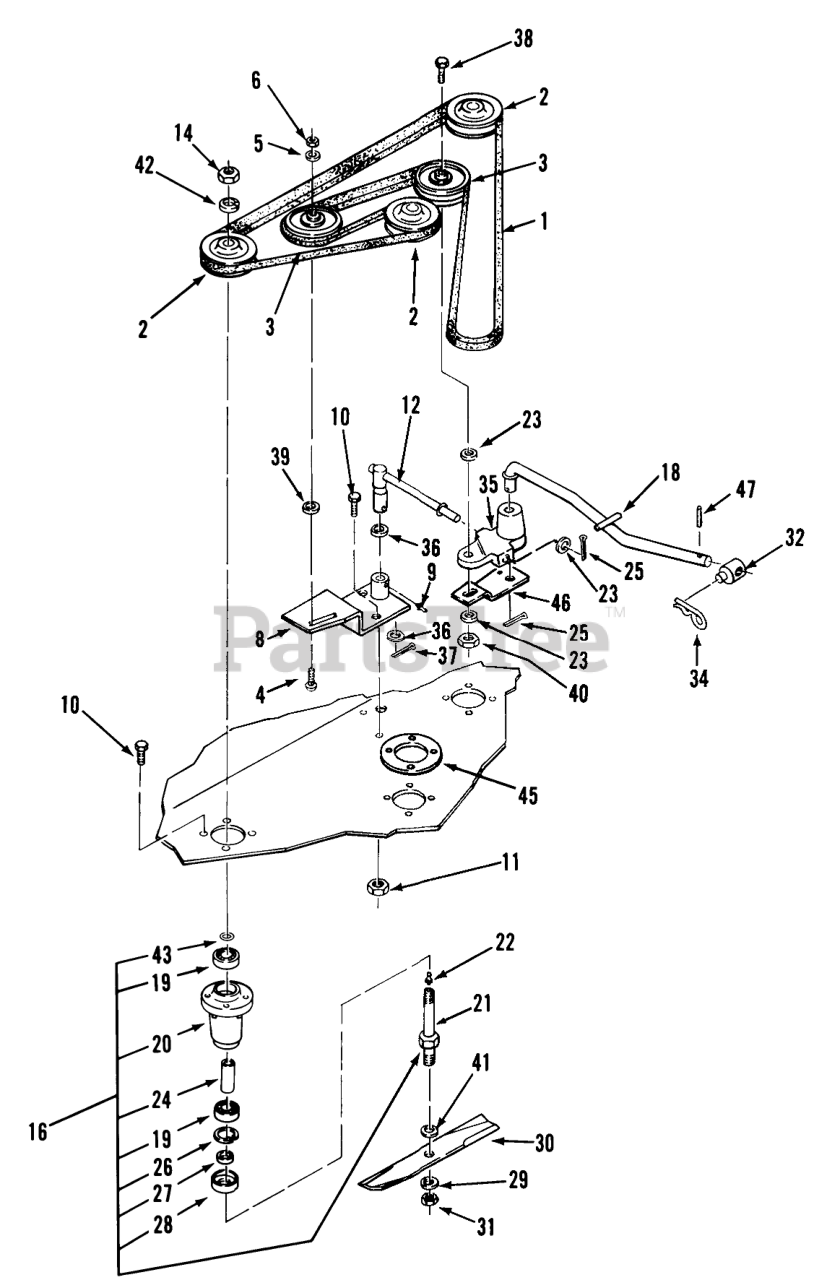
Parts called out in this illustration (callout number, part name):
1	BELT-MOWER
2	PULLEY-BLADE
3	PULLEY-FLAT IDLER
4	Carriage Bolt 3/8-16 x 2
5	Washer
6	NUT
8	Idler Bracket
9	FITTING-GREASE
10	Bolt
11	NUT
12	ASS'Y-IDLER ARM B
14	Jam Nut
16	Spindle Assembly (includes items 19 thru 22, 24, 26 thru 28 & 43)
18	ASS'Y-ROD IDLER
19	BEARING-BALL
20	HOUSING-SPINDLE
21	SHAFT-SPINDLE
22	Zerk
23	Washer
24	Spacer
25	Pop Rivet
26	Ring-Snap
27	SPACER-BLADE
28	CUP-SPINDLE
29	SpeciaI Washer
30	S/A BLADE KIT
31	Nut-Jam
32	TRUNNION-LIFT
34	Hairpin Cotter
35	BLOCK IDLER
36	WASHER
37	Cotter Pin
38	Bolt
39	PAD-SHORT R
40	NUT
41	Washer
42	Lockwasher
43	O RING
45	PLATE-SPINDLE
46	ANCHOR-SPRING B
47	Pin-Roll
